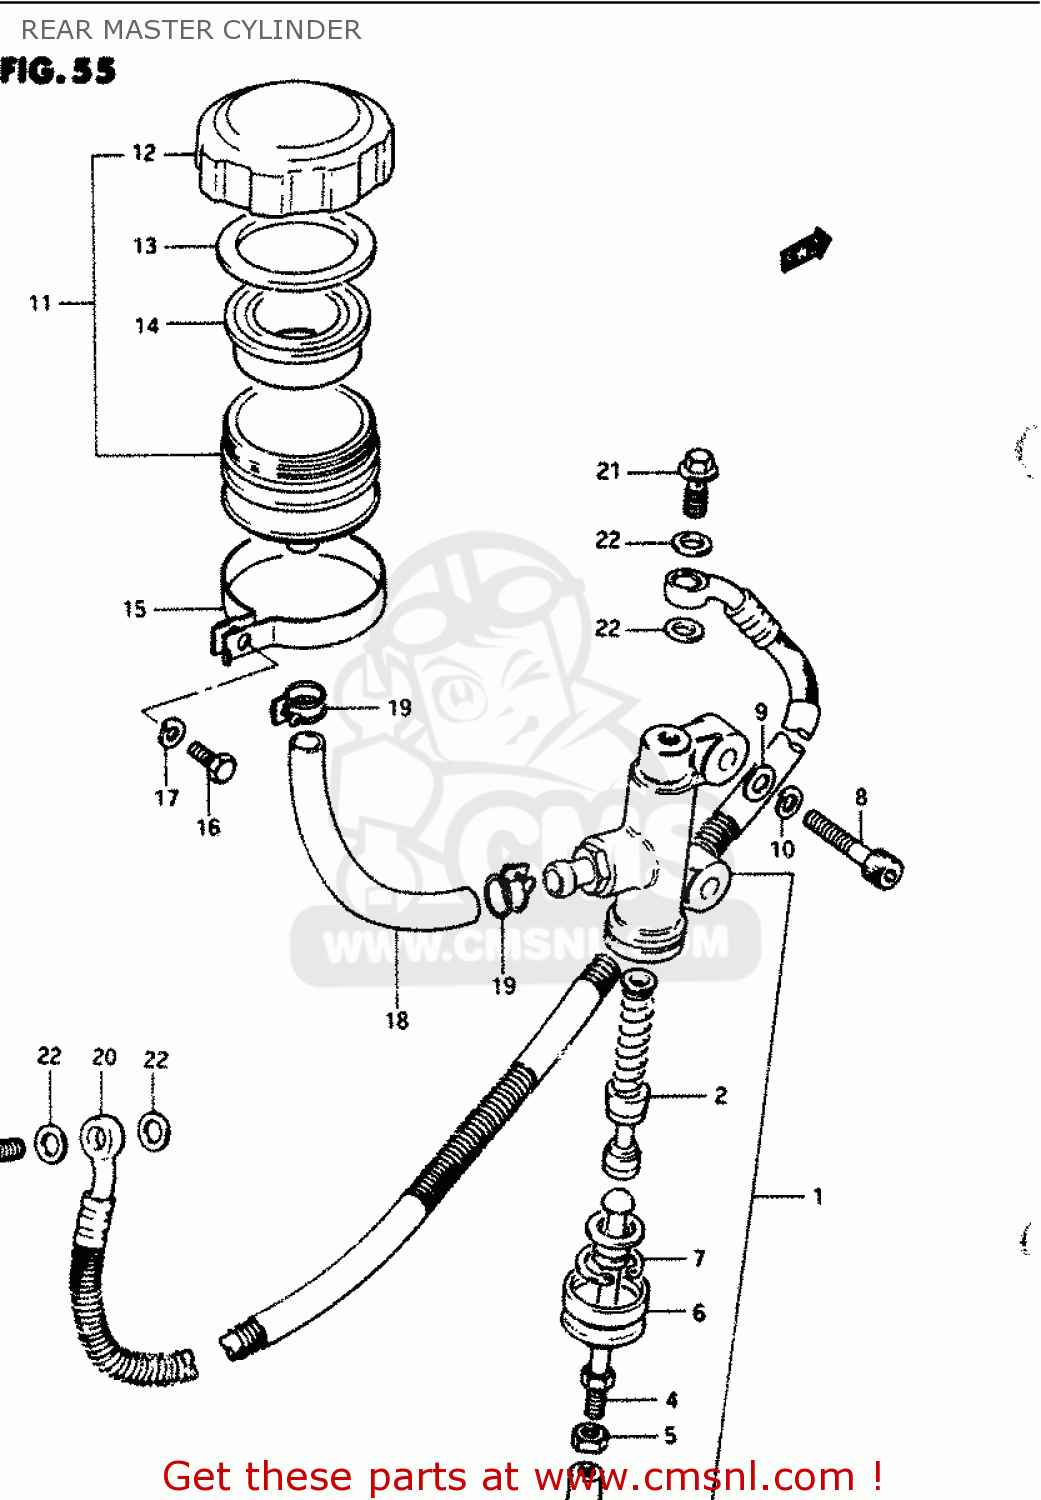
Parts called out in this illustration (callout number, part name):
1	CYLINDER ASSY,RR MASTER
2	PISTON/CUP SET
3	YOKE
4	ROD,REAR MASTER CYLINDER
5	NUT,MASTER CYLINDER
6	BOOT
7	CIRCLIP
8	BOLT, REAR (8X30)
9	WASHER
10	LOCK WASHER
11	RESERVOIR TANK ASSY
12	CAP
13	PLATE,DIAPHRAGM
14	DIAPHRAGM
15	CLAMP
16	BOLT, UPPER
17	WASHER,LOCK
18	HOSE,RESERVOIR TANK
19	CLAMP
20	HOSE,REAR BRAKE
21	BOLT UNION
22	WASHER(10X15X1.5)
